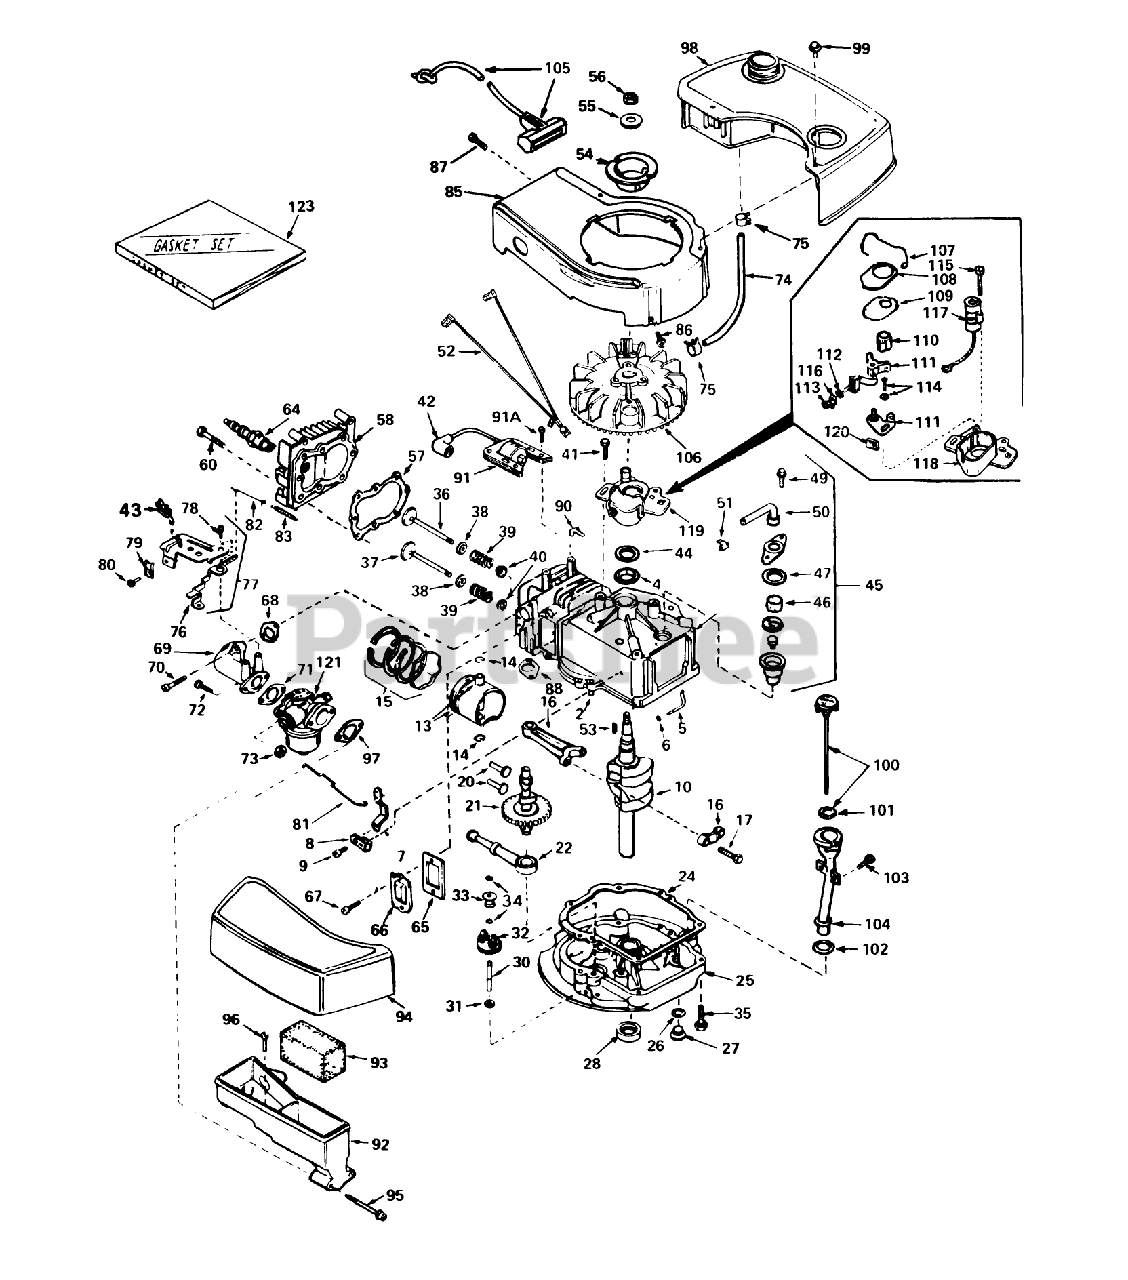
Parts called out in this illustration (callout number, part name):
1	Cyiinder Assy. (Incl. Ref. #2, 4 105)
2	Pin-Dowel
4	Seal-Oil
5	Rod, Governor (Incl. No. 36)
6	Washer-Flat
7	Governor Lever
8	Clamp-Lever, Governor
9	Screw
10	Crankshaft
13	Piston Pin Assy. (Incl . Ref. . #14) (Std.)
13	Piston, Pin Ring Assy. (Std.)(Incl. Ref. #13A, 14 15)
13	Piston Pin Assy. (Incl. Ref. #14) (.010 Oversize)
13	Piston,Pin Ring Assy. (.010 over-size)(Incl. Ref. #13A, 14 15)
13	Piston Pin Assy. (.020 oversize) (Incl. Ref. #14)
13	Piston, Pin Ring Assy. (Incl. Nos. 13A, 14 15)(.020 oversize)
14	Ring-Retaining, Piston Pin
15	Ring Set Piston (Std.)
15	Ring Set Piston (.010 Oversize)
15	Ring Set Piston (.020 Oversize)
16	Rod Assy., Connecting (Incl. Ref. #17)
17	Bolt-Rod, Connecting
20	Lifter-Valve
21	Camshaft(Mech.Comp. Release)
22	Oil Pump ASM
24	Gasket, Mounting
25	Flange Assy., Mounting (Incl. Ref. #26thru 30)
26	Gasket-Oil Drain
27	Plug Oil Drain
28	Seal Oil
30	Shaft-Governor
31	Washer-Flat
32	Governor Gear ASM
33	Spool-Governor
34	Ring-Retaining
35	Screw (1/4-20 x 1-1/4)
36	Valve, Intake (Incl. Ref. #38, 39 40) (Std.)
36	Valve, Exhaust (1/32" Oversize) (Incl. Nos. 8, 9 10)
37	Valve, Exhaust (Standard) (Incl. Nos. 8, 9 10)
37	Valve, Exhaust (1/32" Oversize) (Incl. Nos. 8, 9 10)
38	Cap-Upper Valve Spring
39	Spring-Valve
40	Cap-Valve, Spring
41	Screw
42	Cover-Spark Plug
43	Terminal
44	Gasket Stator
45	Breather Assy. (Incl. Ref. #46, 47, 49, 50 51 )
46	Element-Breather
47	Gasket, Breather
49	Screw, Hex Hd. w/Conical
50	Tube, Breaker
51	Clip, Breather
52	Wire Ground
53	682488 LB GRASS HI-
54	Hub-Starter
55	Washer-Belleville
56	Nut-Flywheel
57	63573 GIL 42 SNWTHW
58	Head-Cylinder
60	Screw (5/16-18x1-1/2)
64	Plug, Spark (J17LM or equiv.)
64	Plug, Spark (Champion RCJ-8)
65	Gasket-Breather
66	Cover-Valve
67	Screw
68	Gasket, Intake
69	Pipe, Intake
70	Screw (1/4-20 x 1)
71	Gasket-Carburetor
73	Nut and Lock Washer (1/4-28)
74	Line-Fuel
75	Clamp-Line, Fuel
76	Lever Control
77	Control Assy., Speed (Incl. Nos, 76, 78 89)
78	Screw, Hex Washer Hd Shoulder Self-Tap
79	Conduit
80	Screw (10-32 x 3/8)
81	Link-Throttle
82	Link Governor Spring
83	Spring Governor
85	Housing Blower
86	Screw
87	Screw (10-24 x 9/16)
88	Gasket Exhaust
90	Clip-Wire
91	Lamination Coil Assy. (Incl. No. 42)
91A	Screw
92	Body Air Cleaner
93	Filer, Air
94	Cove, Air Cleaner
95	Screw Fil Hd.
96	Screw, Hex Hd.
97	Gasket-Air Cleaner
98	Tank, Fuel
99	Screw (10-32 x 35/64)
100	Dipstick, Oil (Incl. Ref. #101)(Twist Lock)
101	O-Ring
102	Gasket
103	Screw (10-32 x 1/2)
104	Tube-Oil Fill
105	Rope Assy., Starter
106	FIywheel
107	Spring Breaker Box
108	Cover-Dust
109	Gasket-Dust Cover
110	Cam-Breaker
111	Breaker Assy.
112	Washer
113	DECAL
114	Breaker Screw
115	Condenser Screw
116	Terminal, Ground
117	Condenser
118	Stator Plate
119	Stator Plate Assy. (incl. Nos. 107, 111 thru 118 120)
120	Felt,Cam Wiper
121	Carburetor (Incl. Ref. #71 )
123	53024/VAR.16HP O/P
